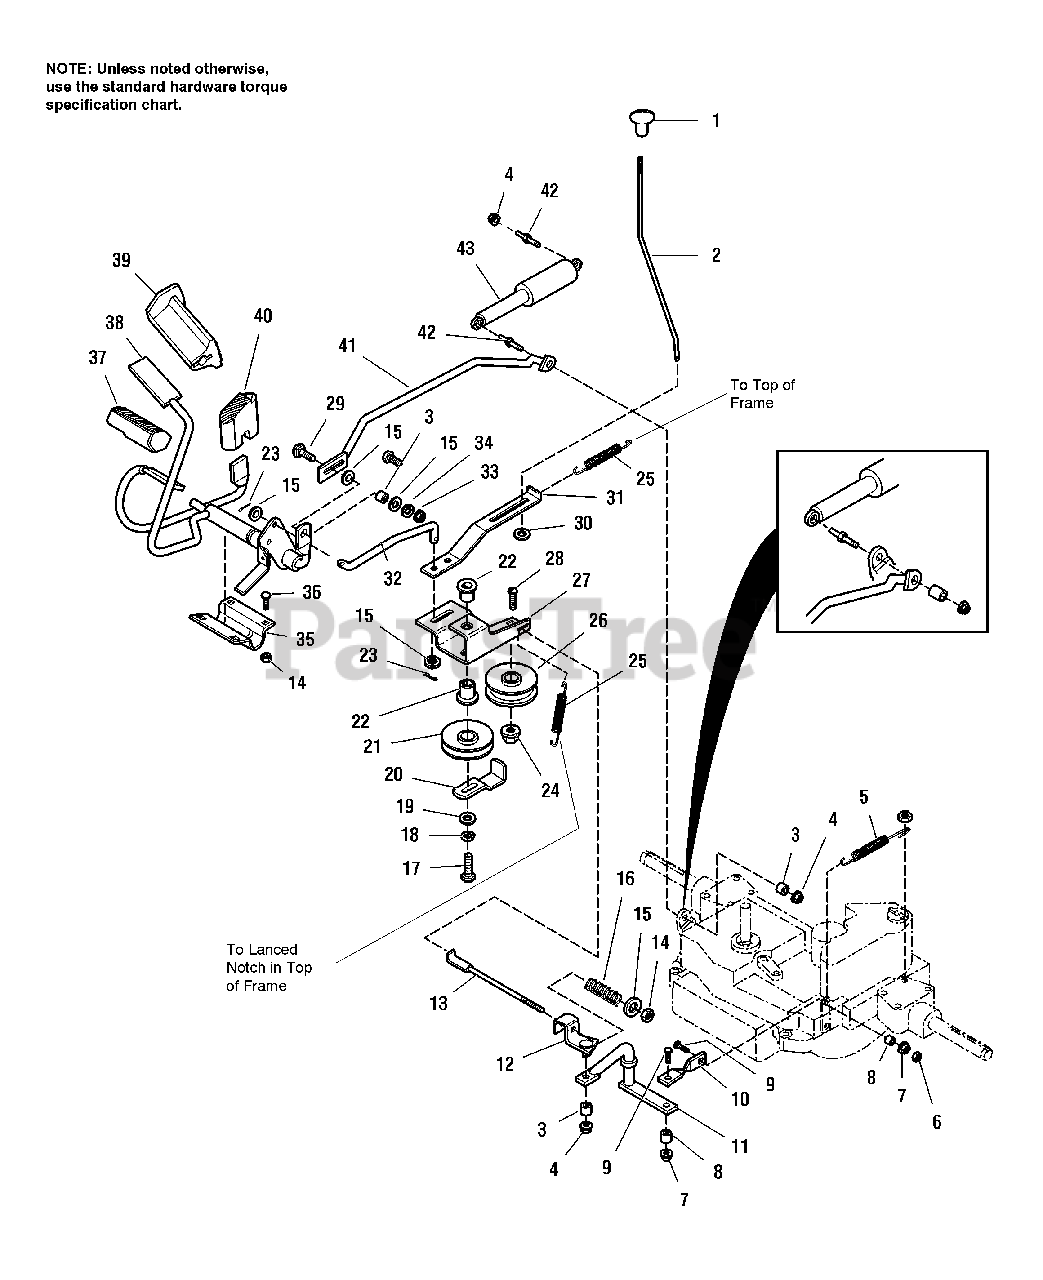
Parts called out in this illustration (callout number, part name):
1	KNOB, Plastic, Parking Brake
2	ROD, Parking Brake
4	NUT, Hex Flange Lock, 5/16-18
5	SPRING, Brake Return
6	LOCK NUT, Center, 1/4-20
7	NUT, Hex Flange Lock, 1/4-20
9	CAPSCREW, Hex Hd, 1/4-20 x 1
12	GUIDE, Brake Rod
14	NUT, Hex Nylon Lock, 5/16-18
15	WASHER, Plain, 5/16
17	CAPSCREW, Hex Hd, 3/8-16 x 1-3/4
18	LOCKWASHER, 3/8
19	WASHER, Plain, 3/8
21	PULLEY, Idler, V
22	BUSHING, 5/8
23	COTTER PIN, 1/8 x 3/4
24	NUT, Hex Flange Whiz Lock, 3/8-16
26	PULLEY, Backside Idler
27	BRACKET, Idler
28	CARRIAGE BOLT, 3/8-16 x 1-3/4
29	CARRIAGE BOLT, 5/16-18 x 1
30	WASHER, Plain, 1/4
31	LEVER, Parking Brake
32	ROD, Clutch
33	NUT, Hex, Full, 5/16-18
34	LOCKWASHER, 5/16
35	CLAMP, Tube
36	CARRIAGE BOLT, 5/16-18 x 3/4
37	PAD, Foot Pedal, Forward
38	FOOT PEDAL ASSEMBLY
39	PAD, Brake Pedal
40	PAD, Foot Pedal, Reverse
41	ROD, Control
42	STUD, Shock Mounting
43	SHOCK ABSORBER
